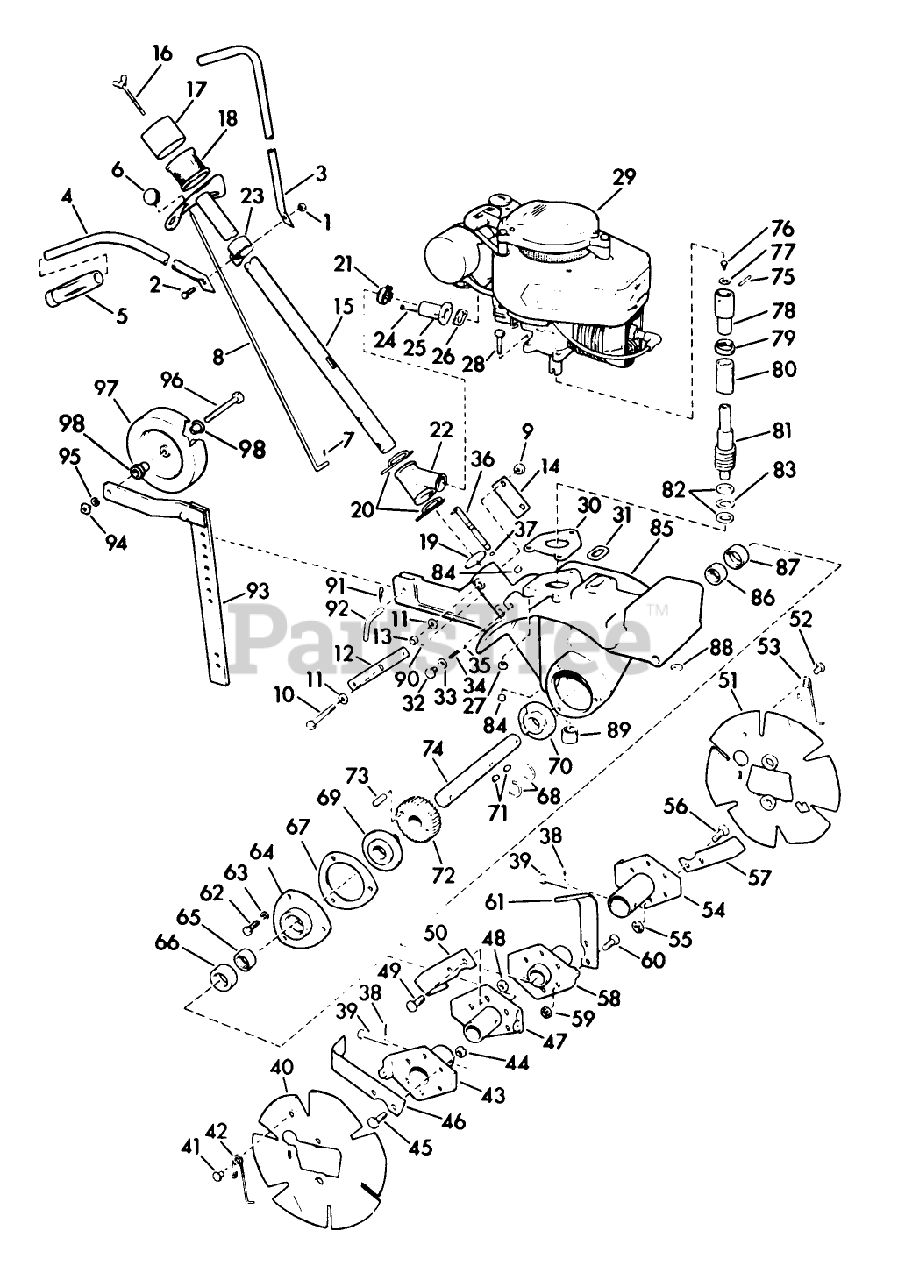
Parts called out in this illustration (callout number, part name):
3	Handlebar Section-Left
4	Handlebar Section-Right
6	Knob-Control Rod
7	Cotter Pin
8	Rod-Control
9	LOCKNUT
10	Screw-Hex Head Cap
12	Cotter Pin
13	Spacer-Control Rod Lever
14	Clamp-Handlebar Support Tube
19	Seal-Dust, Felt
20	Clamp-Hose
22	Tee-Carburetor, Rubber
23	Clamp-Handlebar
25	Tube-Carb. to Handle
32	Screw-Hex Head, Nylok
33	Washer-Plain, Aluminum
34	Spring-Detent
35	Ball-Detent
36	Clutch Pin Control Assy.
37	Ring-"O", Clutch Pin
39	Pin-Tine Assy. Attachment
41	Rivet-Shoulder
42	Spring-Trim Plate, Right
45	Screw-Hex Head Cap
46	Tine-Right Hand
49	Screw-Hex Head Cap
50	Tine-Right Hand
52	Rivet-Shoulder
53	Spring-Trim Plate, Left
56	Screw-Hex Head Cap
57	Tine-Left Hand
60	Screw-Hex Head Cap
61	Tine-Left Hand
65	Bearing
67	Gasket-Housing Cover
68	Ring-Retaining
70	Ratchet-Clutch, Left
72	Gear-Worm
73	Pin-Ratchet
74	Shaft-Worm Gear
75	Pin-Clutch
76	Screw-Hex Head, Nylok
77	Washer-Thrust
78	Coupling-Clutch Drum
79	Spring-Clutch Shock
82	Race-Thrust
83	Bearing-Needle Thrust
86	Bearing
89	Bearing-Closed End
92	Pin-Selector
95	WASHER, LOCK
